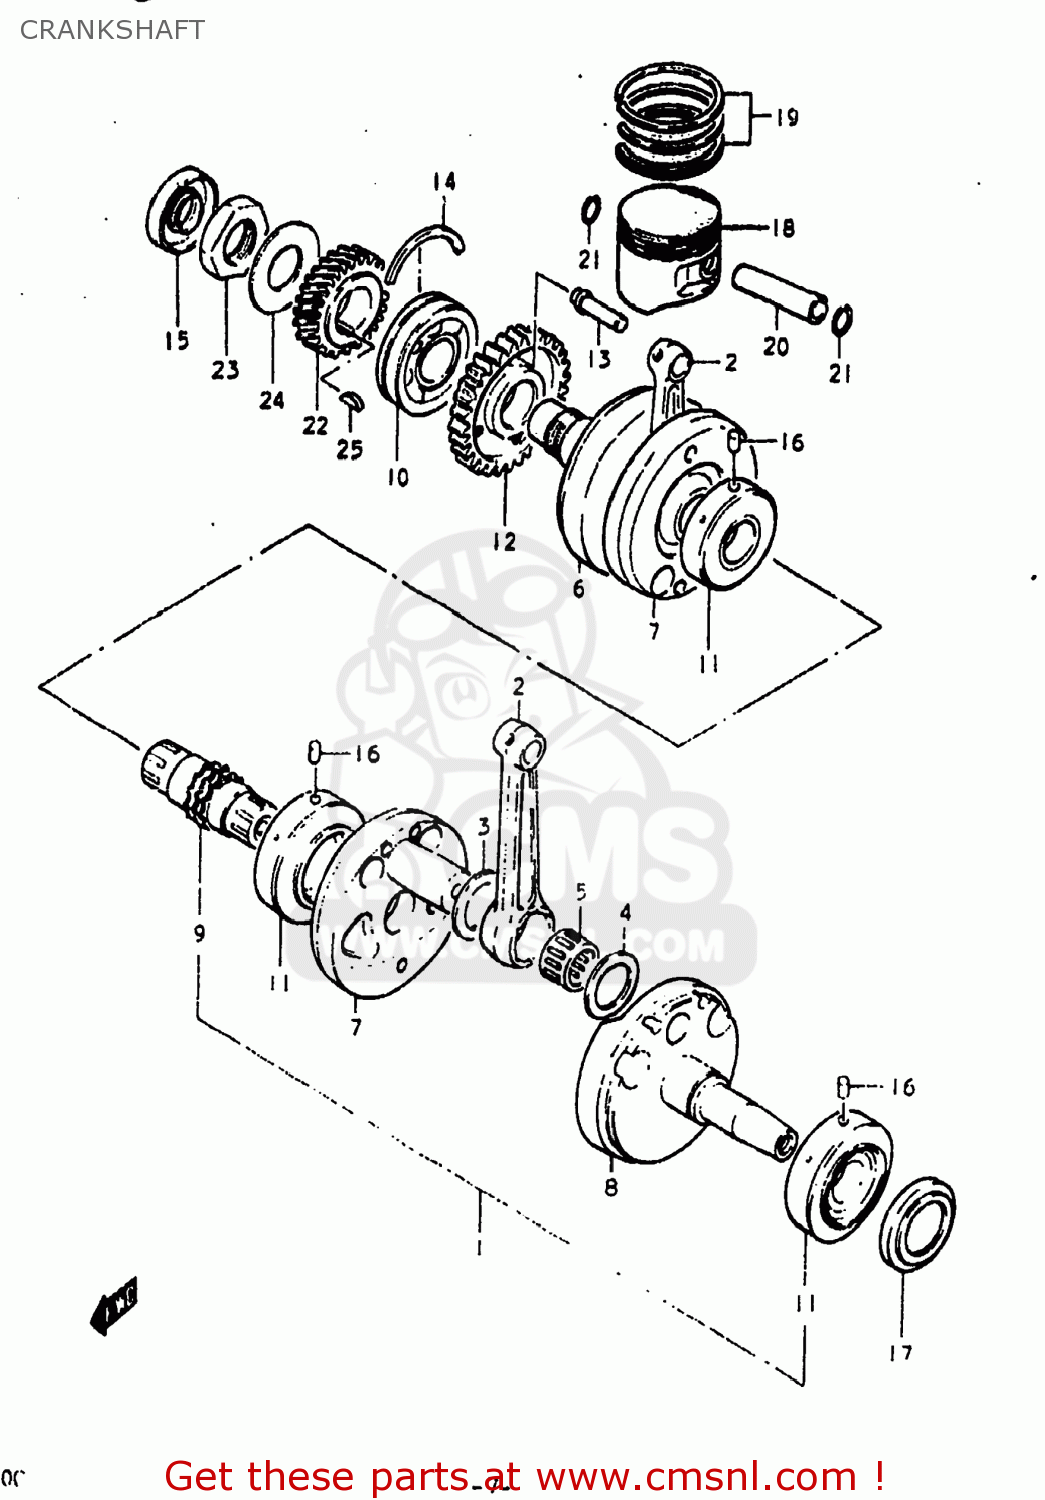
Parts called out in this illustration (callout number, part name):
1	CRANKSHAFT ASSEMBLY
2	ROD,CONNECTING
3	WASHER (28X48X2)
4	WASHER(28X48X1)
5	BEARING(28X38X19.8)
6	CRANKSHAFT
7	WEB,CRANK
8	CRANKSHAFT,LEFT
9	SHAFT,TIMING CHAIN DRIVE
10	BEARING(30X72X19)
11	BEARING
12	GEAR,CRANK BALANCER DRIVE
13	PIN
14	C RING
15	SEAL,OIL(25X47X8)
16	PIN
17	OIL SEAL
18	PISTON
19	PISTON RING SET
20	PIN,PISTON
21	CIRCLIP
22	GEAR,PRIMARY DRIVE
23	NUT
24	WASHER
25	KEY
